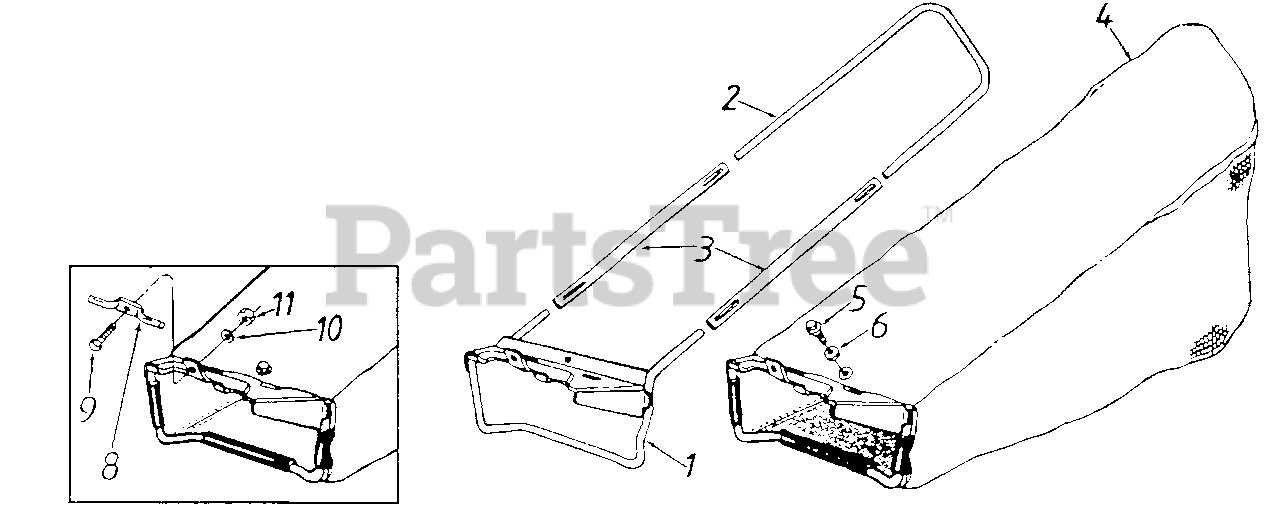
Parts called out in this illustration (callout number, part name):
4	Grass Bag
5	Hex Wash. Hd. TT-Tap Scr. 1/4-20 x 5" Lg.
6	Bell-Wash. 1/4" I.D.
8	Grass Bag Hook
9	Hex Bolt 1/4-20 x .62" Lg.
10	L-Wash. 1/4" I.D.
11	Hex Nut 1/4-20 Thd.
